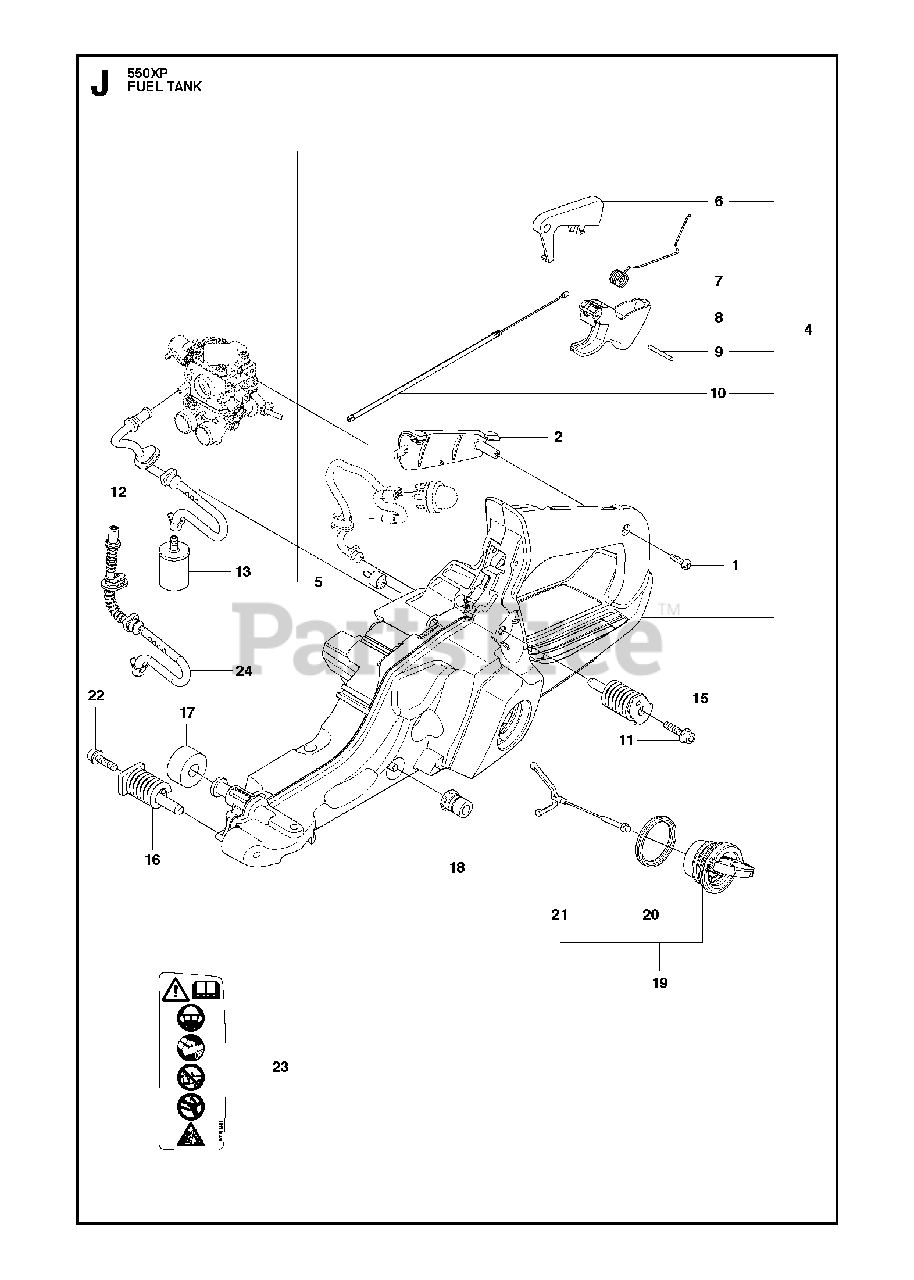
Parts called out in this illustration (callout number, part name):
2	HANDLE INSERT
4	FUEL TANK ASSY 50CC ORANGE
5	Tank Vent Assembly
6	THROTTLE LOCKOUT
7	SPRING
8	THROTTLE
9	PIN
10	THROTTLE CABLE ASSY
12	FUEL HOSE
13	FUEL FILTER
15	ANTIVIBRATION ELEMENT
16	ANITVIBRATION ELEMENT
17	DEFLECTION LIMITER
18	LATERAL SUPPORT
19	TANK CAP ASSY
20	SEALING
21	TANK LOCK
23	DECAL
24	FUEL HOSE
